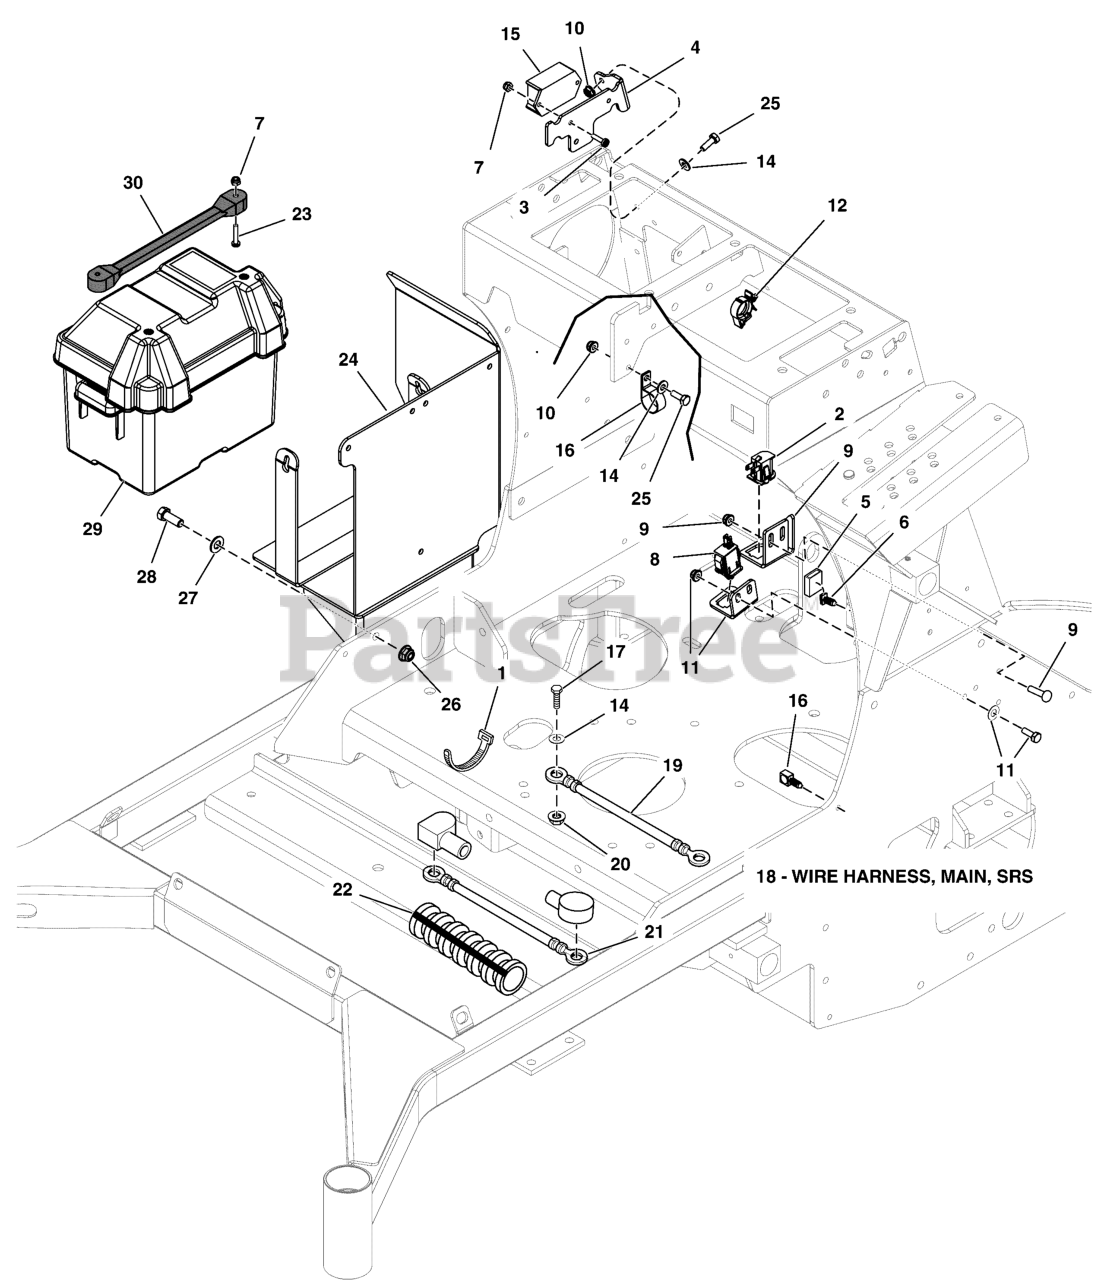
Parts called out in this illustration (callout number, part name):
1	TIE, SELF-LOCKING, 12"
2	SWITCH, Push Button, NO, Black
3	SCREW, #10-24 X 3/4" ROUND PHILLIPS
4	PLATE, WIRE GUIDE / TDM MOUNT - BLK
5	PART OF WIRE HARNESS
6	FIR TREE MOUNT, PACKARD
7	NUT, Hex, Nylon Lock, #10-24
8	SWITCH, PLUNGER, NO, SINGLE POLE, SNAP-IN
9	Refer to: Operator Compartment Group
10	NUT, 1/4-20 Hex Nylock Flange
11	Refer to: Parking Brake Group
12	ROSEBUD LOOM CLIP
13	BATTERY, 11U1L, 350 CCA
14	WASHER, 1/4 SAE
15	MODULE, TIME DELAY, NO DIODE
16	CLAMP, VINYL INSULATED, 1.00
17	HHCS, 1/4-20 X 0.625, GR5, ZINC/CLEAR
18	HARNESS, Wiring, Stand-On ZTR
19	BATTERY CABLE, NEG, 22, 1/4-5/16
20	NUT, 1/4-20 HEX SERR. FLANGE
21	BATTERY CABLE, POS, 22, 1/4-5/16
22	WIRE LOOM, 3/8 ID X 19 IN
23	SCREW, #10-24 X 1 RS, CZ
24	WELD, BATTERY BOX, STAND ON - RED
25	BOLT, 1/4"-20 X 3/4" GD5 YZ
26	NUT, 3/8 - 16 HEX NYLOCK FLANGE
27	WASHER, 3/8 SAE
28	BOLT, 3/8-16 X 1" GD5 CZ
29	BATTERY BOX, W/ DRAIN HOLE
30	STRAP, RUBBER
